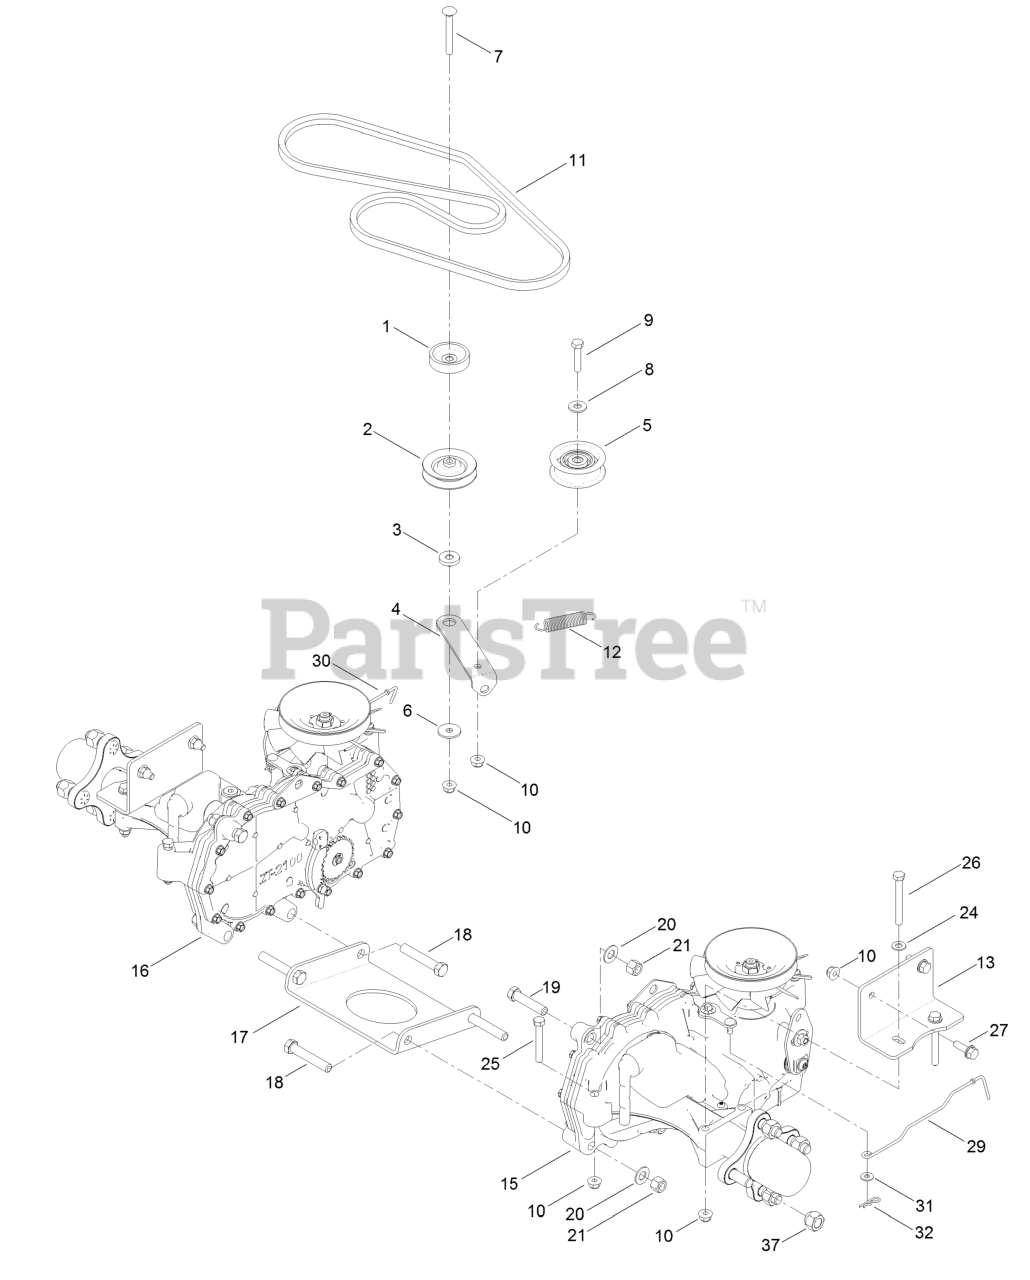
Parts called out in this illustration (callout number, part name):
2	Pulley-Idler
3	Spacer-Arm, Idler
4	Arm-Idler
5	Pulley-Idler
6	Washer-Pivot
7	Screw-CARR
8	Washer-Flat
9	Screw-HH
10	Nut-HF, NI
11	V-Belt
12	Spring-Return, Pedal
13	Mount-Hydro
15	LH Hydro Transaxle ASM
16	RH Hydro Transaxle ASM
17	Plate-Cross, Hydro
18	Screw-HH
19	Screw-HH
20	Washer-Flat
21	Nut-Lock, NI
24	Washer-Plain
25	Screw-HH
26	Screw-HH
27	Screw-HHF
29	Rod-Bypass, LH
30	Rod-Bypass, RH
32	Pin-Cotter
37	Nut-Lug
